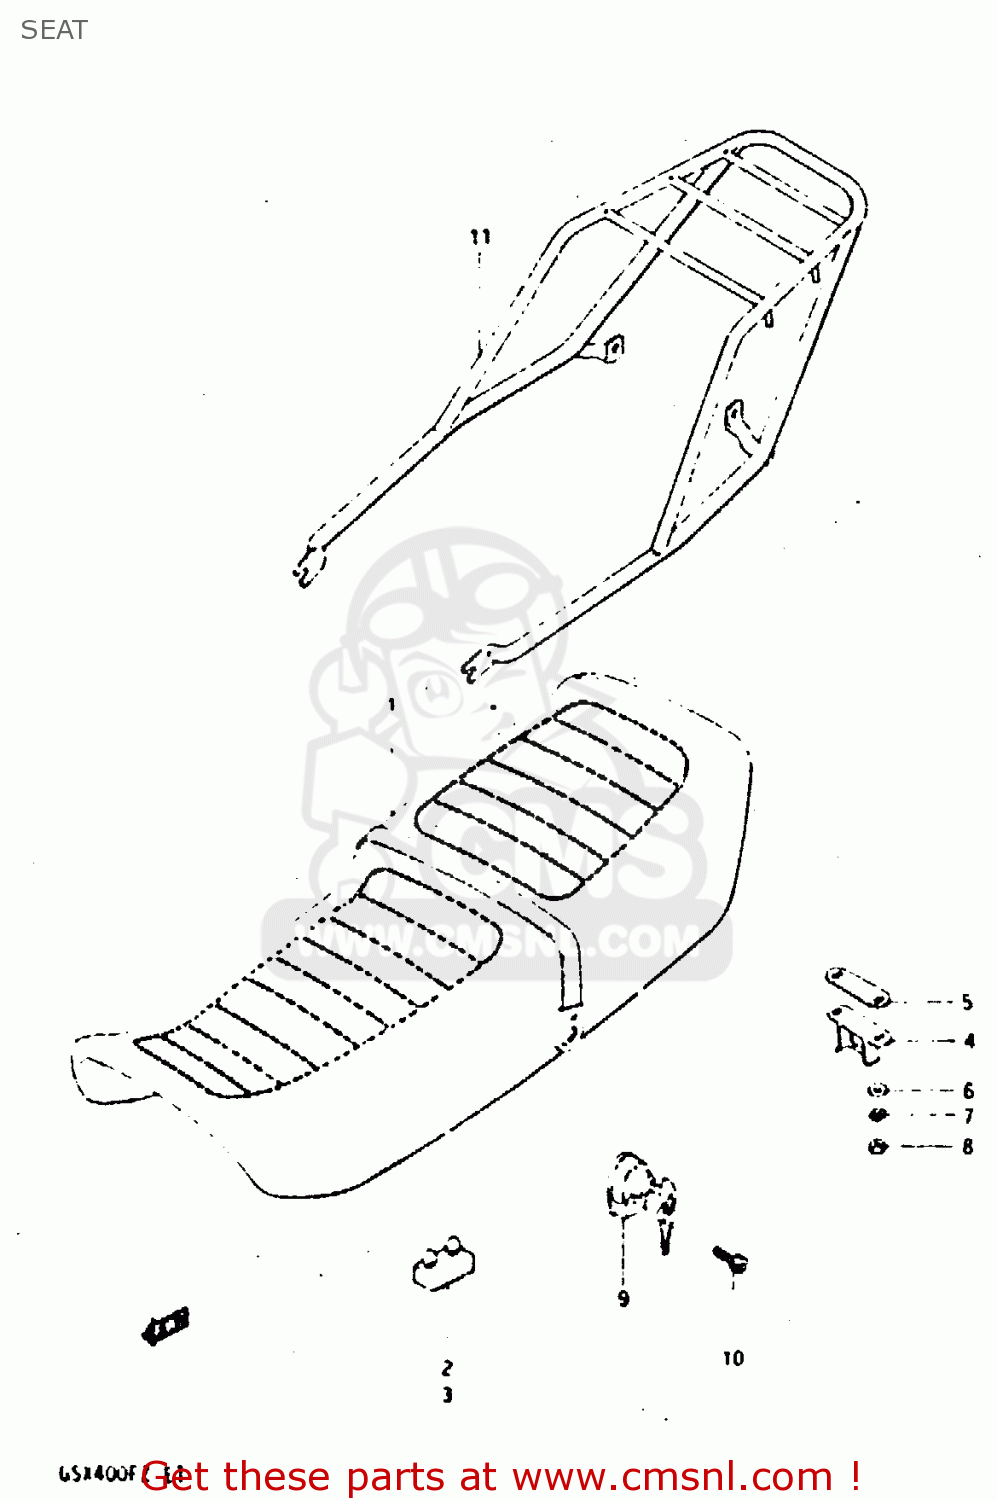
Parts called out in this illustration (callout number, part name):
1	SEAT ASSY (BLACK)
2	CUSHION
3	CUSHION
4	STRIKER, SEAT LOCK
5	SHIM,SEAT LOCK STRIKER
6	WASHER
7	LOCK WASHER
8	NUT 6MM
9	LOCK ASSY,HELMET
10	BOLT 5X25
11	CARRIER, SPORTS
